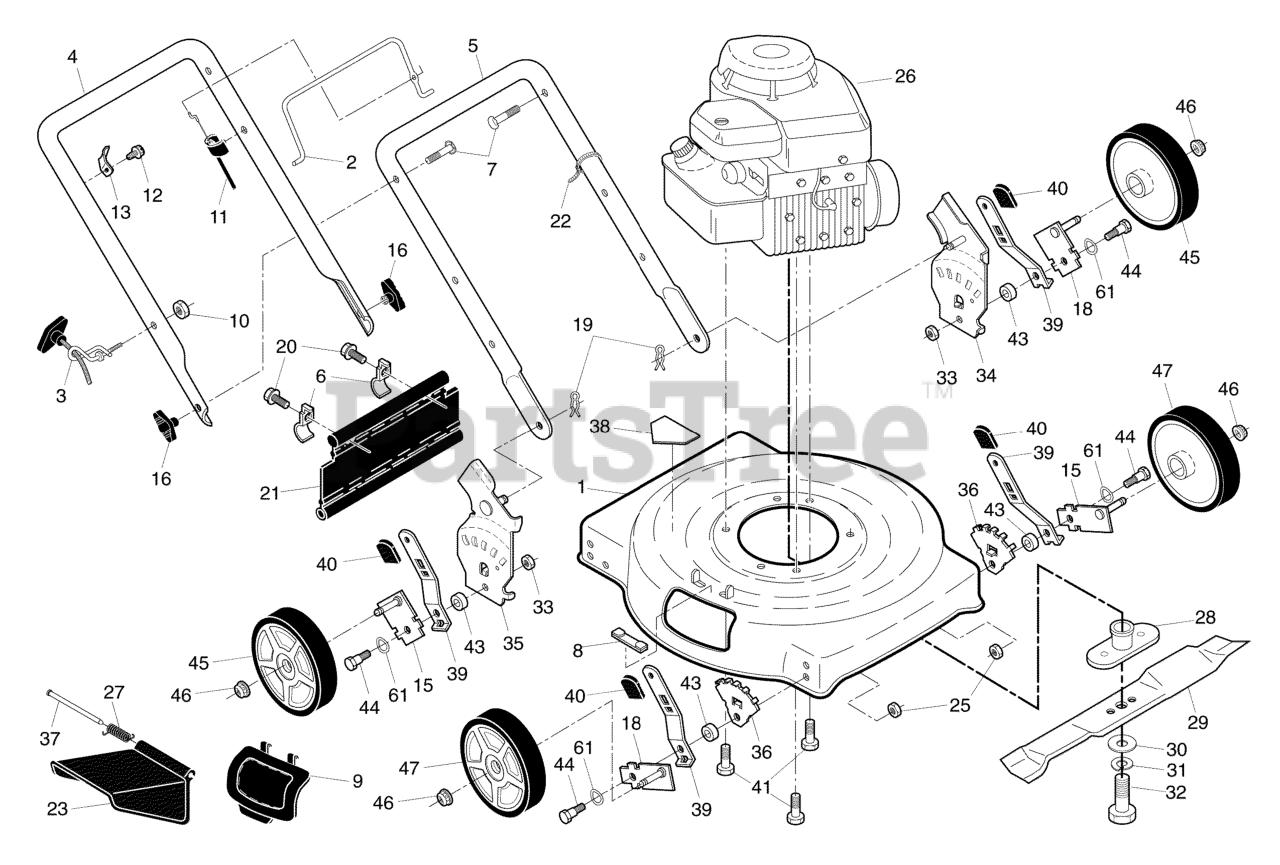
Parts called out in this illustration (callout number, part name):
1	** KIT, Housing (Includes Key Number 38)
2	CONTROL BAR
3	GUIDE, Rope
4	HANDLE, Upper
5	HANDLE, Lower
6	BOLT, Shoulder, 5/16-18 x 1/2
7	BOLT, Handle, 5/16-18
8	CLIP, Closeout
9	MULCHER PLATE
10	LOCKNUT, Hex, 1/4-20
11	** CABLE, Engine Zone Control
12	SCREW, Hex Head, Threaded, Rolled, #10-16 x 5/8
13	BRACKET, Upstop
15	AXLE ARM ASSEMBLY, Left Front & Right Rear
16	KNOB, Handle
18	AXLE ARM ASSEMBLY, Right Front & Left Rear
19	Hairpin Cotter
20	SCREW, Tapping, Hex Washer Head #10-24
21	DEFLECTOR, Rear
22	Wire Tie
23	GUARD, Discharge
25	NUT, Hex, Flangelock 5/16-18
26	* ENGINE, Briggs & Stratton
27	SPRING, Torsion
28	ADAPTER, Blade
29	BLADE, 22"
30	WASHER, Hardened
31	LOCKWASHER, Helical, 3/8
32	SCREW, Hex Head, 3/8-24 x 1-3/8, G8
33	NUT, Hex, Flangelock 5/16-18
34	SUPPORT, Wheel Bracket, LH
35	SUPPORT, Wheel Bracket, RH
36	ADJUSTER, Wheel Bracket
37	HINGE ROD
38	DECAL, Danger
39	SPRING, Selector
40	KNOB, Selector
41	SCREW, Hex Head, Threaded, 3/8-16 x 1
43	SPACER
44	BOLT, Shoulder, 5/16-18 x .33
45	WHEEL & TIRE ASSEMBLY, Rear
46	NUT, Hex, Flangelock 3/8-16
47	WHEEL & TIRE ASSEMBLY, Front
53	CLIP, Cable
61	WASHER, Curved, Cylindrical
